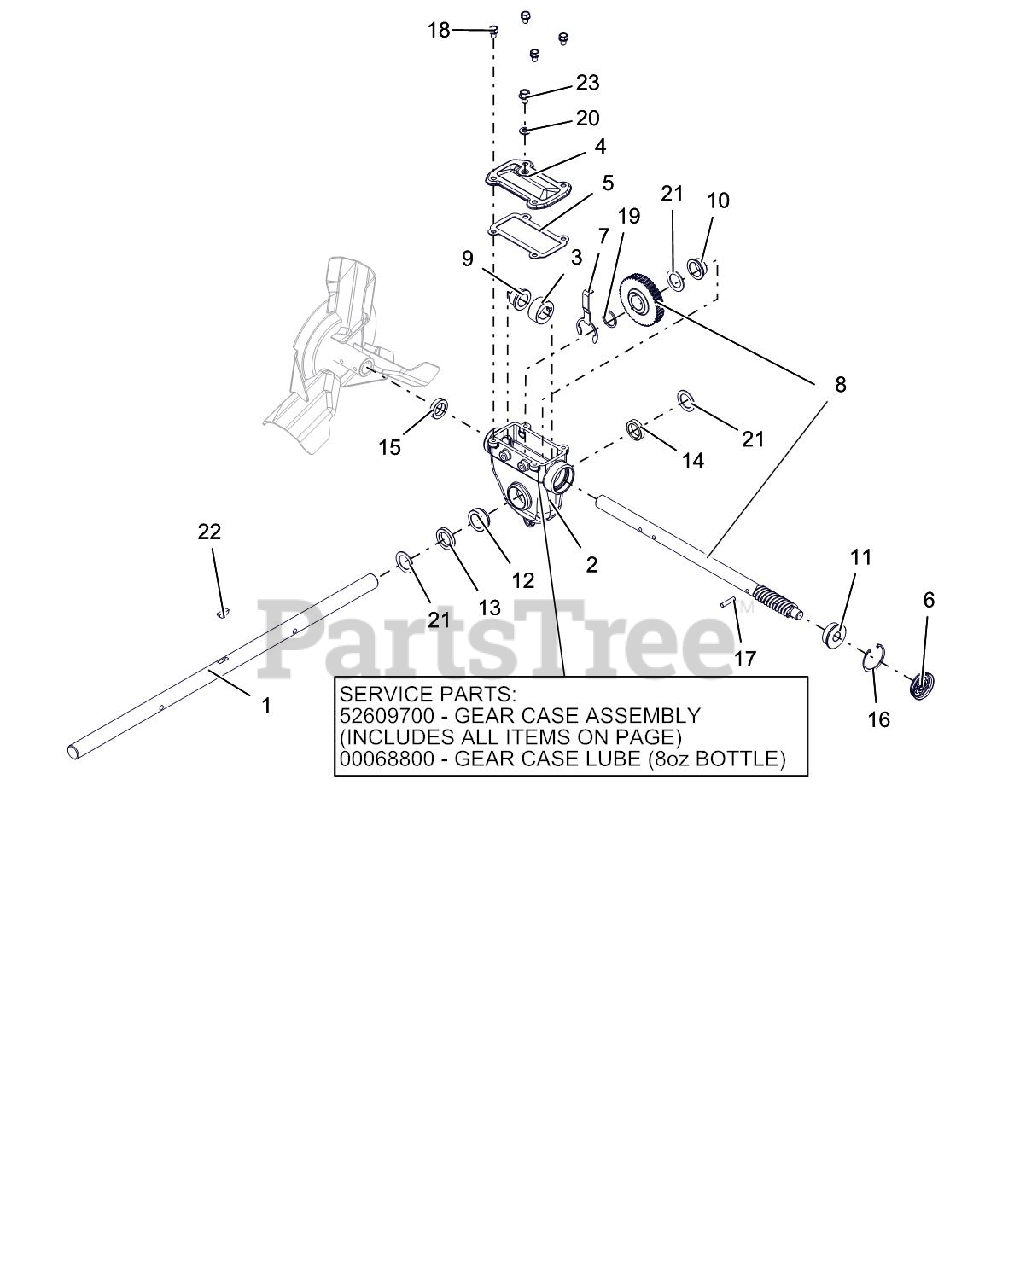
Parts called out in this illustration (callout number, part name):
1	SHAFT, RAKE-28"
2	ARIENS L3 LUBE, 8 OZ BOTTLE
2	GEARCASE, LARGE MACHINED
2	GEAR CASE, 28" IRON PRO TOP-LD
3	THRUST COLLAR, .875"ID SLIPFIT
4	COVER, TOP - LARGE IRON
5	GASKET, TOP - LARGE GEARCASE
6	COVER, GEAR CASE 1.75"
7	BUSHING RETAINER, LARGE
8	ASSY, WORM SHAFT & GEAR
9	BSHG-FLG .879X1.128X.75X1.45
10	BSHG-FLG 1.006X1.128X.555X1.45
11	BSHG-FLG .628X1.503X.58X1.725
12	BSHG-FLG LARGE, RIGHT
13	SEAL-OIL .999X1.500X.250 TBC29
14	SEAL-OIL .999X1.375X.312 TBC29
15	SEAL-OIL .873X1.375X.312 TBC29
16	RG-RTNG-INT 1.750X.062
17	PIN-STR .250X1.12 6150
18	BOLT, SEMS .31-18X.50 GR5 YWZC
19	WSHR-FL-STL 1.010X1.250X.068YZ
20	WSHR-BND-SEAL .38X.75X.11 GALV
21	WSHR-FL-STL 1.010X1.505X.062YZ
22	KEY-WDRF .25X.875 HRD #A
23	@SCR-ROLOK .38-16X.50 HWH YWZC
